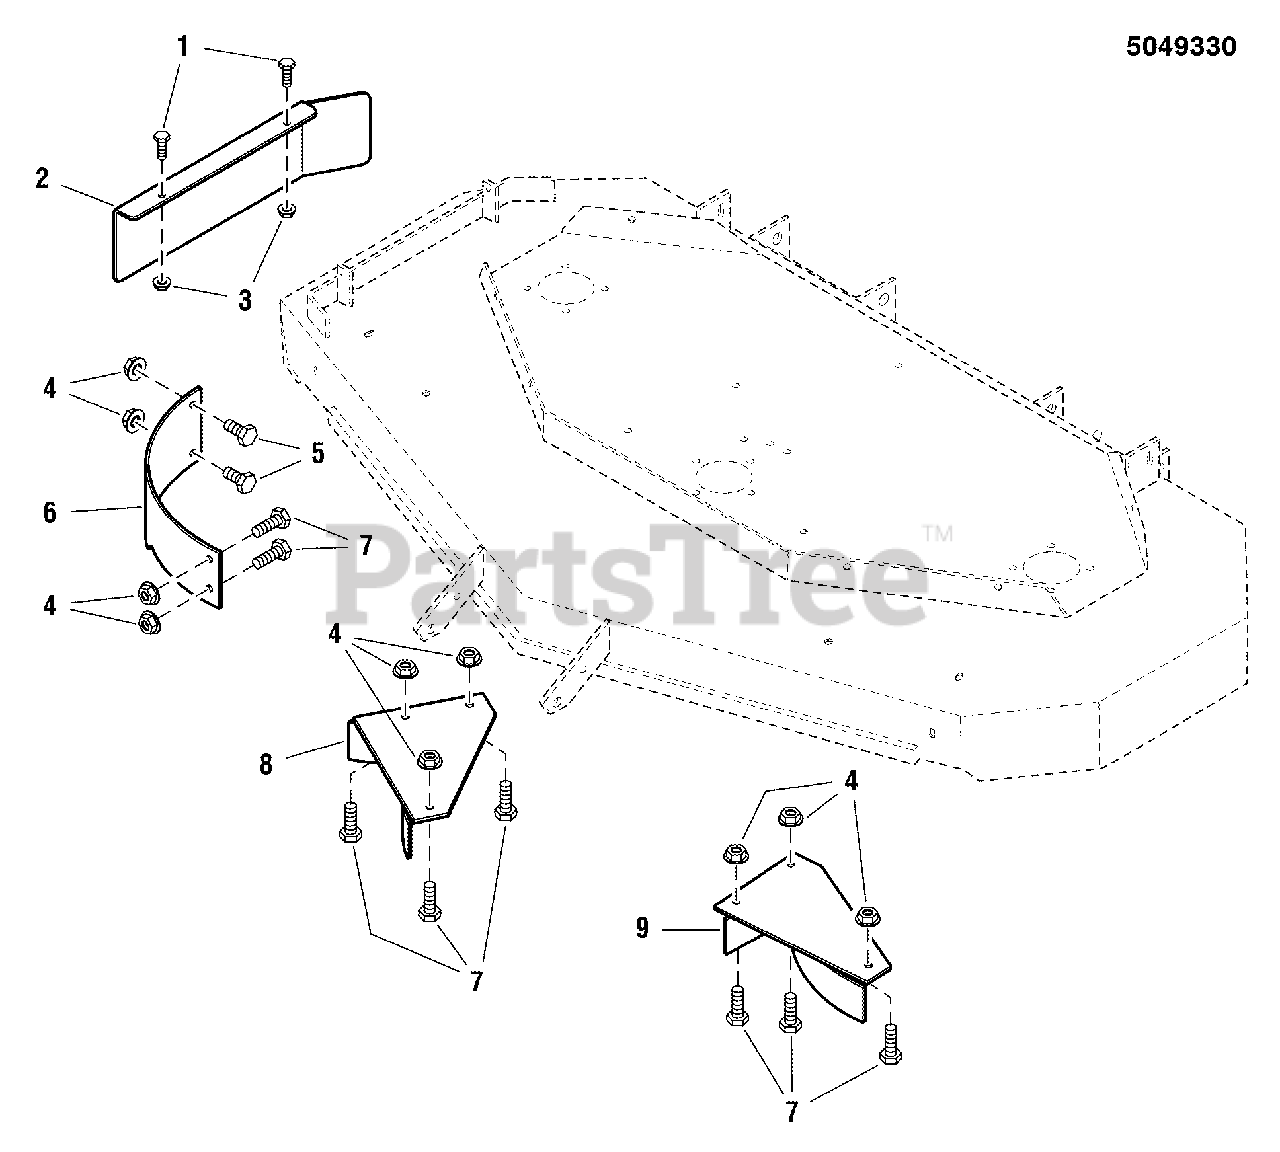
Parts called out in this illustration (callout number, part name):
1	BOLT, 1/4-20 X 3/4, GD5
2	PLATE, Block Off
3	NUT, Hex Nylock Flange, 1/4-20
4	NUT, Hex Nylock Flange, 5/16-18
5	BOLT, 5/16-18 X 5/8, GD5
6	RING, Mulching, RH
7	BOLT, 5/16-18 X 1, GD5
8	Plate, Mulch, RH
9	Plate, Mulch, LH
